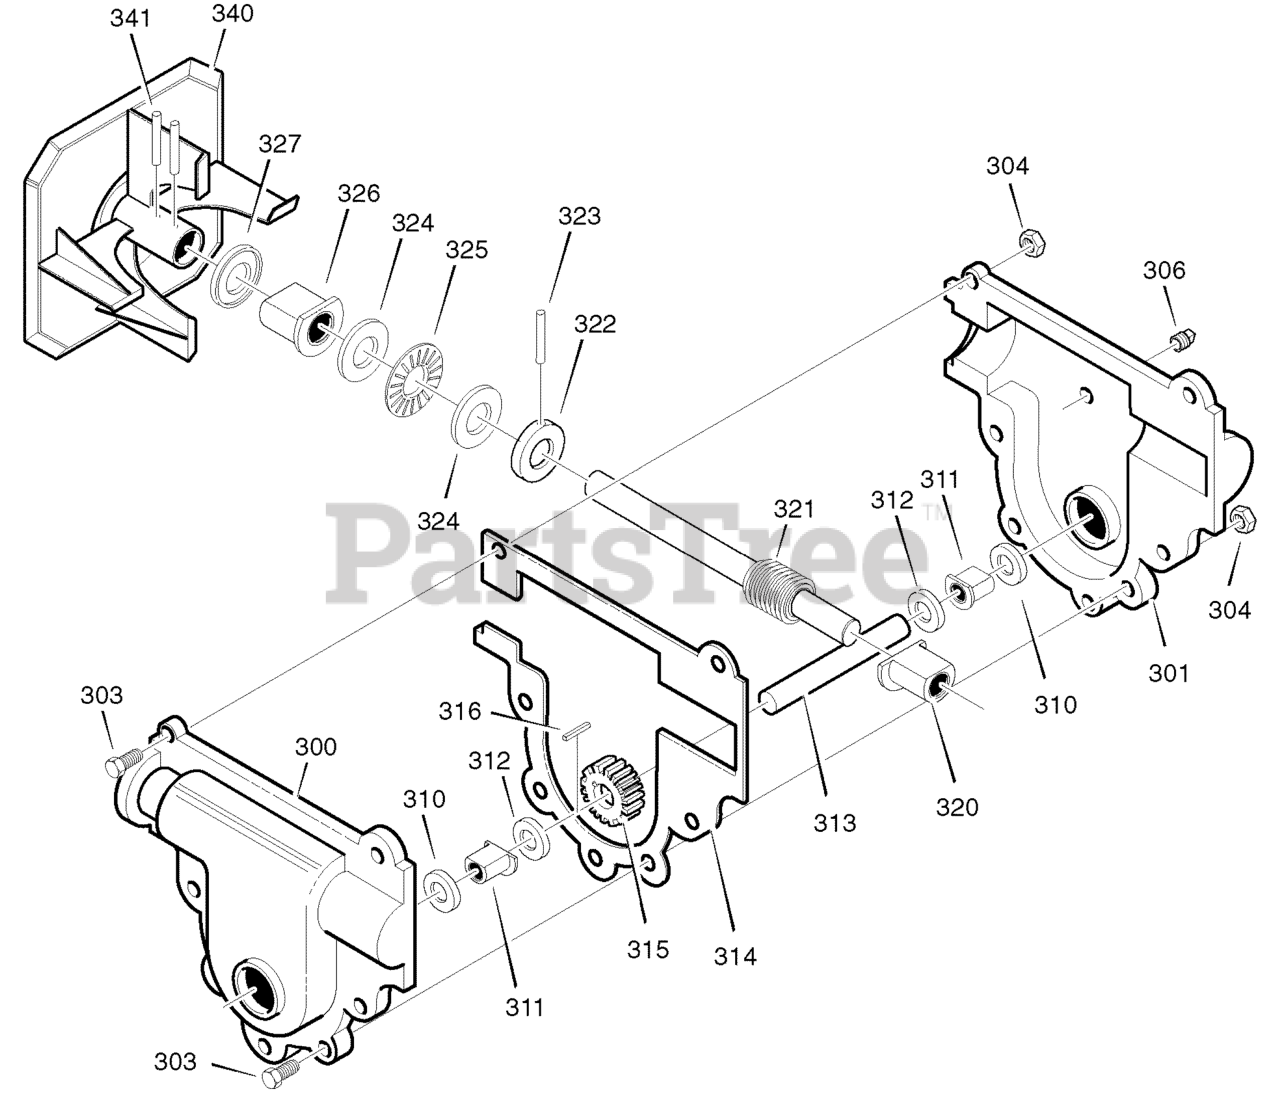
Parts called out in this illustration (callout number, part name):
300	CASE, GEAR, RH
301	CASE, GEAR, LH
303	SCREW,1/4-20X.75
304	NUT,1/4-20
306	SCREW, 3/8-16 x 0.50
310	SEAL, OIL
311	BEARING, FL
312	WASHER, FLAT
313	SHAFT, AUGER OUTPUT
314	GASKET, GEAR BOX
315	GEAR, WORM
316	KEY, WOODRUFF #61
320	BRNG, FL
321	SHAFT, AUGER INPUT (IMPELLER)
322	COLLAR, THRUST
323	PIN, SPRING
324	WASHER, FLAT
325	BRNG, ROLL
326	BRNG, FL
327	SEAL, OIL
341	PIN, SPRING
